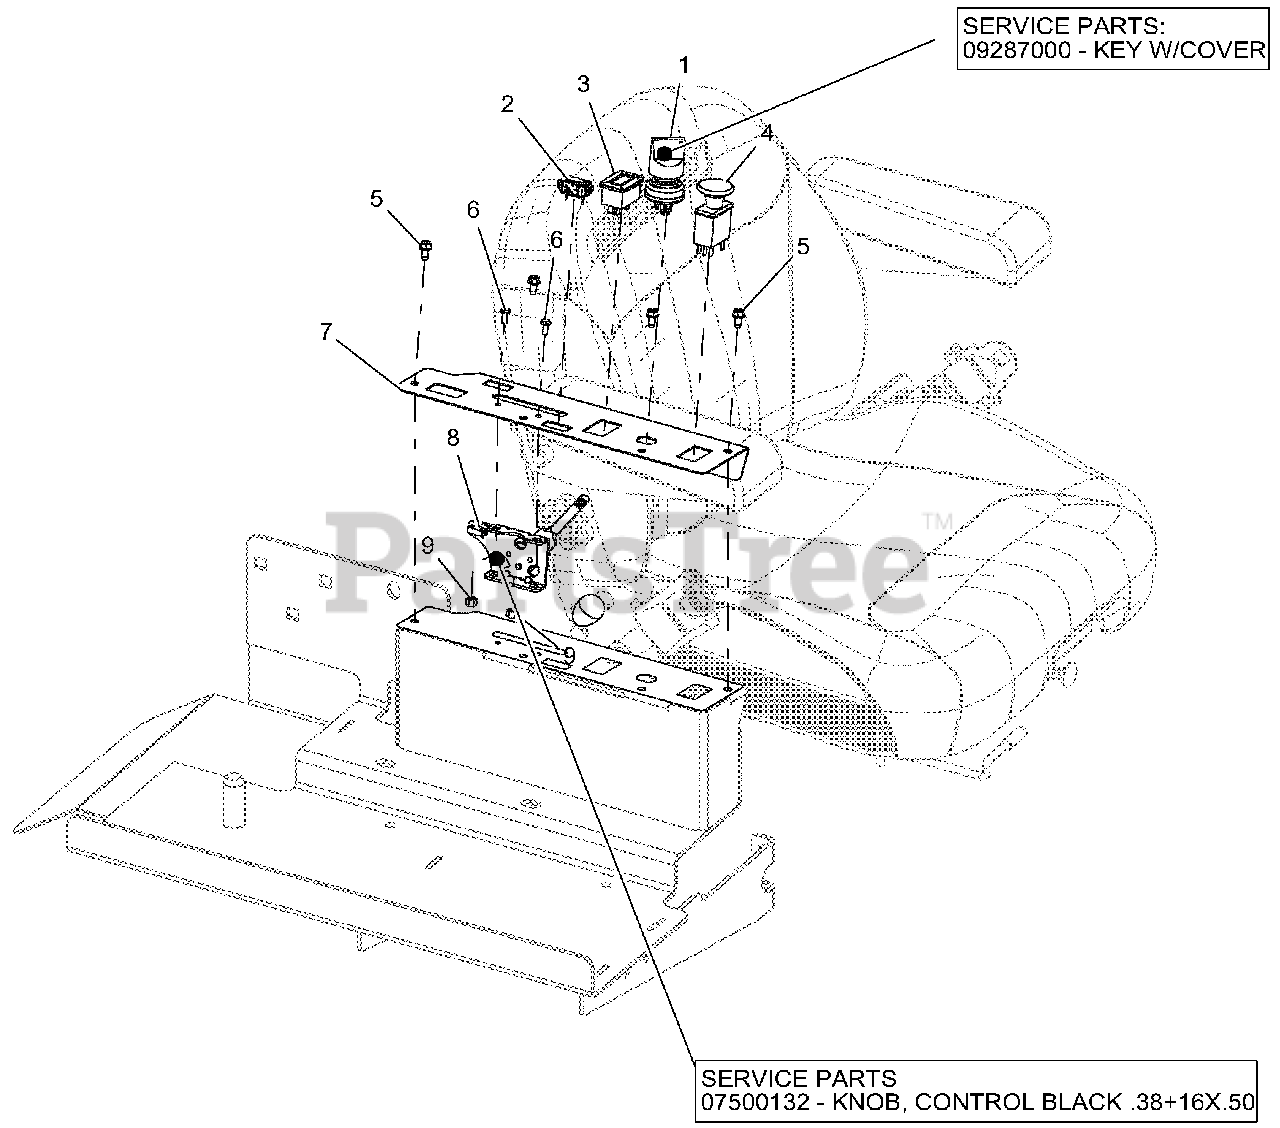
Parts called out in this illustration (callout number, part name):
1	SWITCH, IGNITION
1	KEY W/ COVER
2	LIGHT, INDICATOR
3	METER, HOUR W/MAINTENANCE
4	SWITCH, CLUTCH
5	SCR-TAP .25-20X.50 HWH TR YWZ
6	SCR-MCH 10-24X.5 HWH YWZC
7	PANEL, CONTROL PT40P0 - L
8	CABLE, PRO-CONTROL THROTTLE
8	KNOB, CONTROL BLACK .38+16X.50
9	NUT-LK-NYL #10-24 YWZC
